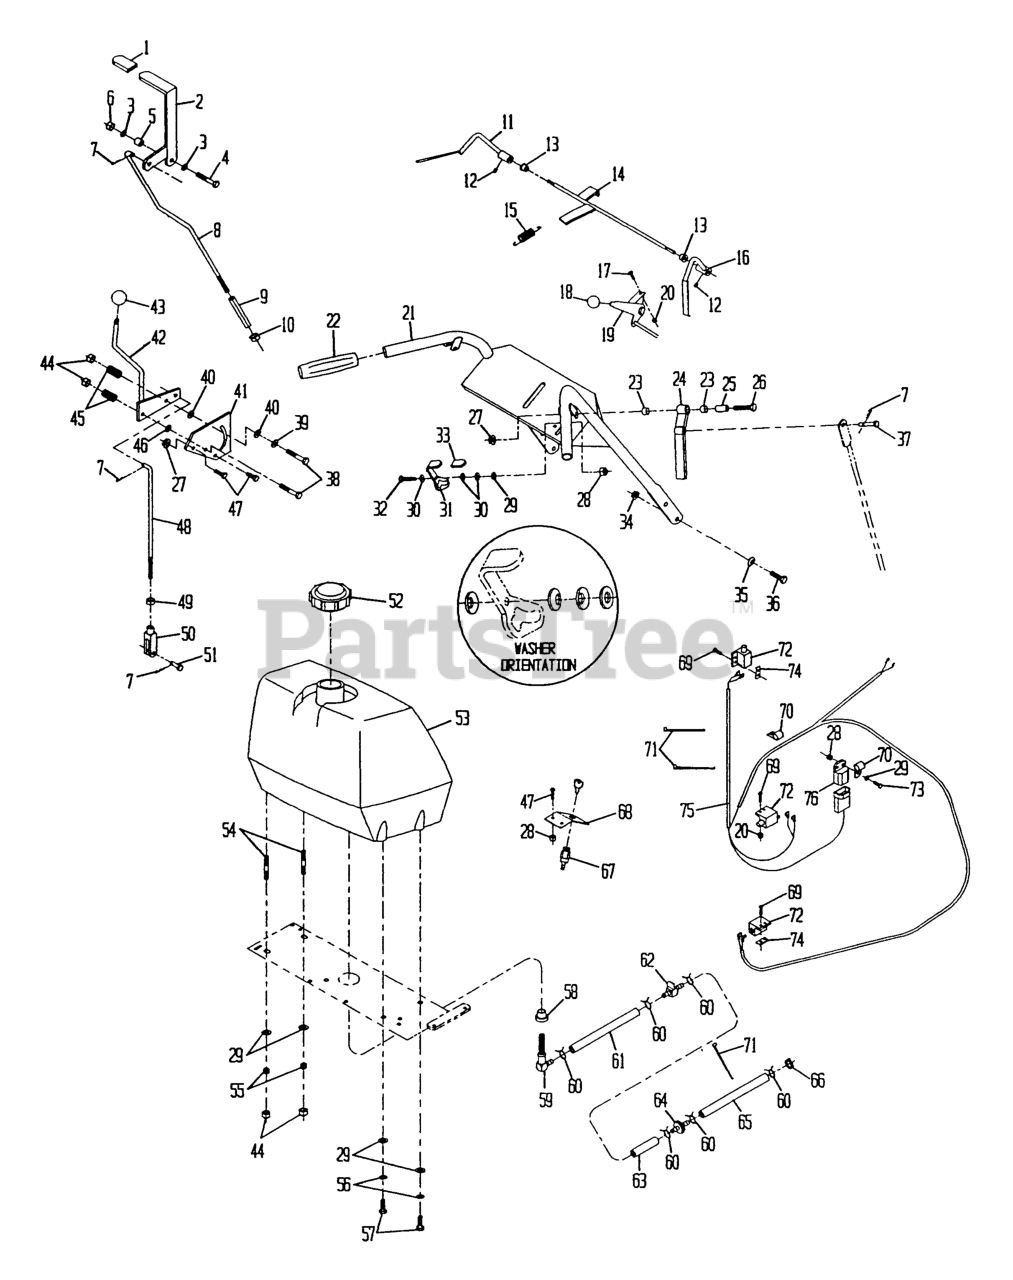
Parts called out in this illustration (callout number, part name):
1	GRIP-LEVER
5	BUSHING-LEVER, LIFT
7	PIN-COTTER
8	LINKAGE,UPPER
9	TURNBUCKLE
11	LEVER-LH
12	SCREW-SET
13	BUSHING-NYLON
14	WLD,ROD OPC
15	SPRING-EXTENSION
16	LEVER-RH
17	BOLT-CARR
18	KNOB-BALL
19	CABLE,THROTTLE CONTROL
23	BUSHING-SLEEVE
25	BUSHING-LEVER, DRIVE
30	WASHER-SPRING
33	GRIP-LATCH
37	PIN-CLEVIS
39	WASHER-FRICTION
40	WASHER-FRICTION
41	PLATE-LEVER, SHIFTER
43	KNOB-BALL
45	SPRING-COMPRESSION
48	ROD,SPEED CONTROL
50	YOKE-ADJUSTABLE
51	PIN-CLEVIS
52	CAP-FUEL
54	STUD
55	SPRING-TANK, FUEL
56	WASHER-LOCK
59	ELBOW-TANK, FUEL
60	CLAMP
61	HOSE-FUEL
62	VALVE-FUEL
63	HOSE-LINE, FUEL
65	LINE-FUEL
66	CLAMP-HOSE
67	SWITCH & KEY (INCLUDES NU
70	CLIP-LOOM
71	TIE-CABLE
72	SWITCH-OPEN, NORMALLY
74	PLATE-TAPPED
75	HARNESS,WIRING KAW TT
76	MODULE-INTERLOCK
